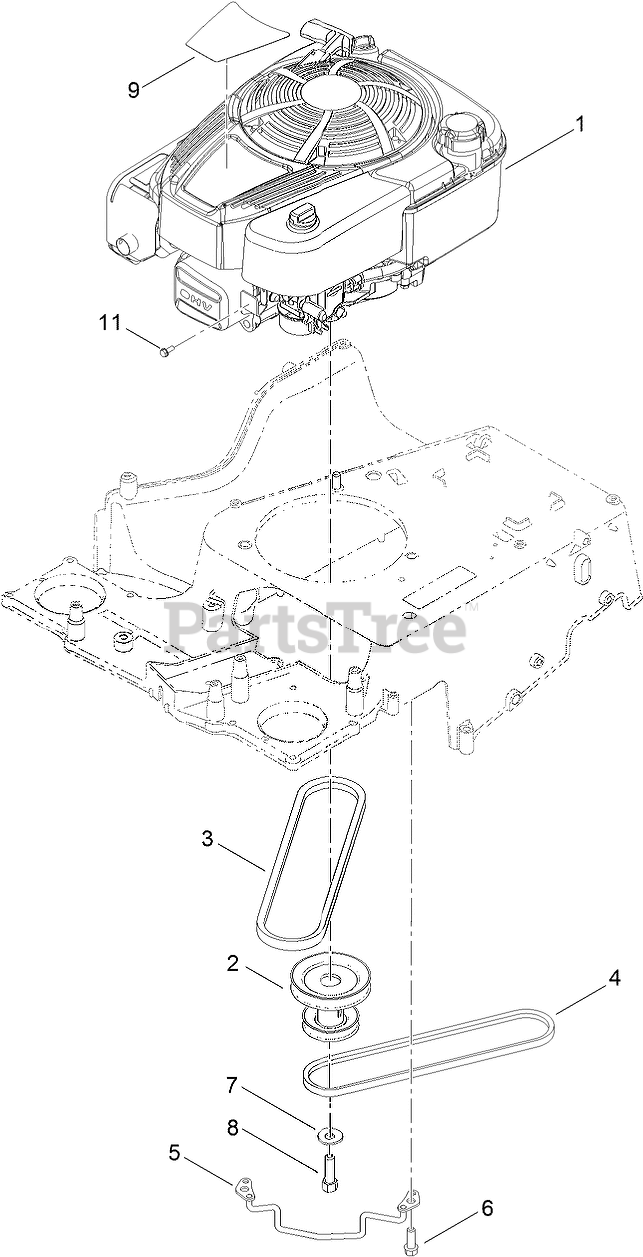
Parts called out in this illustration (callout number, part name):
2	PULLEY-ENGINE
3	V-BELT
4	V-BELT, TRACTION
5	GUIDE-BELT
6	SCREW-TAPTITE
7	WASHER-BELLEVILLE
8	SCREW-HH
9	DECAL-SHROUD
11	SCREW-TAPTITE
